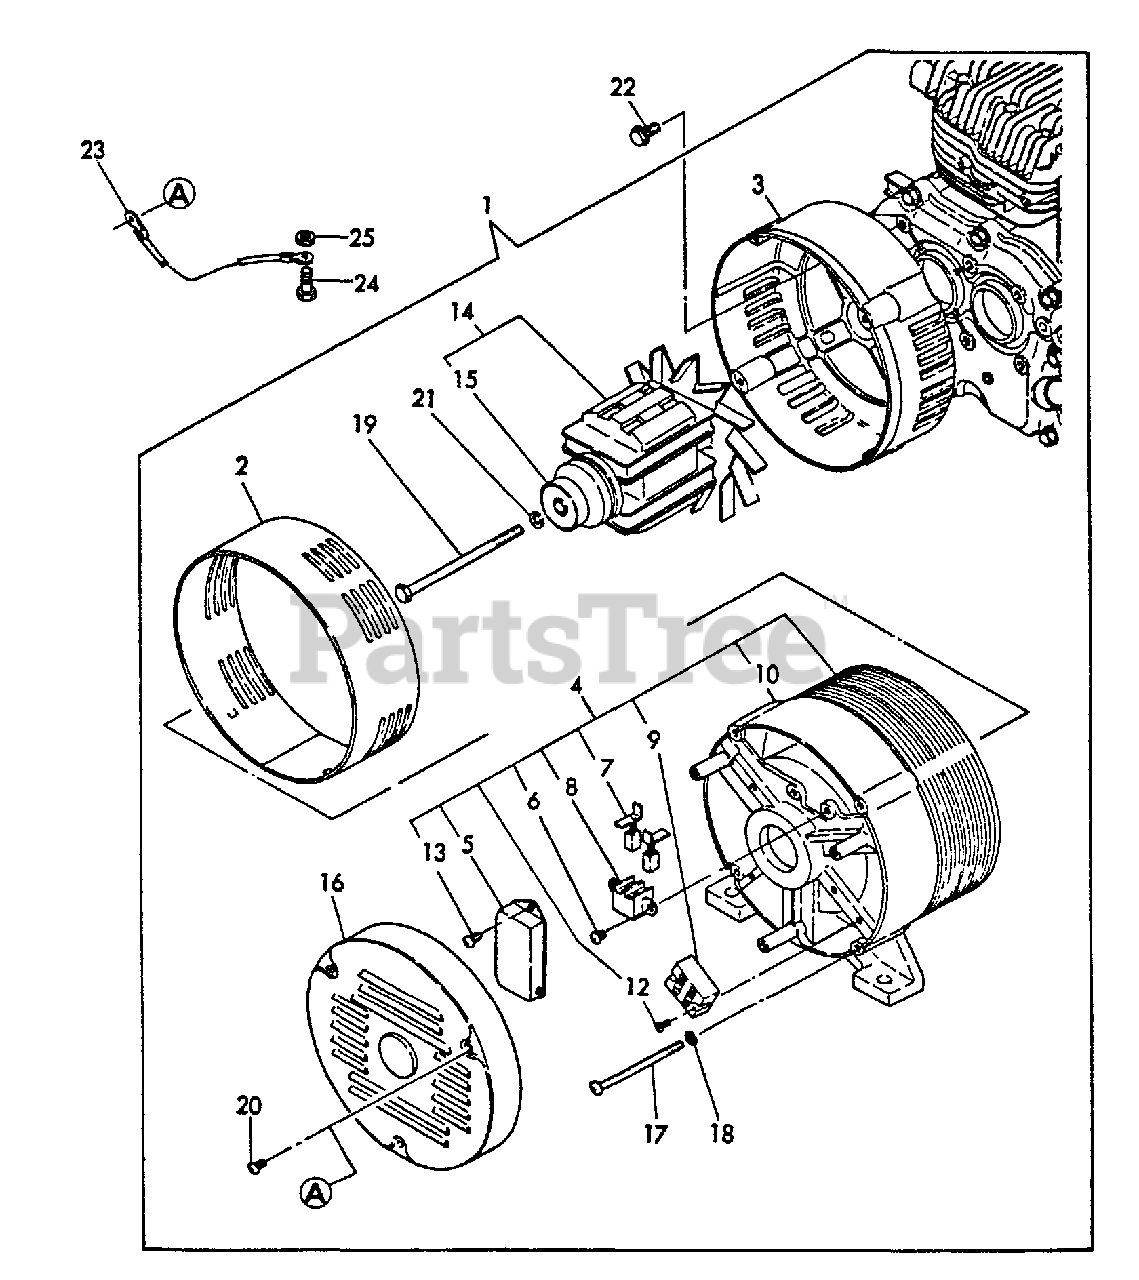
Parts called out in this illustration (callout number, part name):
1	GENERATOR 3.0 KVA
2	CLAMP
3	COVER - FRONT
4	STATOR ASSY
5	A.V.R.
6	SCREW - 5X14
7	BRUSH ASSY
8	HOLDER, BRUSH
9	TERMINAL
10	COVER - REAR
12	SCREW - 5X14
13	SCREW - 4X10
14	ROTOR ASSY
15	BEARING, BALL
16	COVER, END
17	BOLT, THROUGH
18	LOCKWASHER - 6
19	BOLT
20	SCREW - 4X10
21	LOCKWASHER - 10
22	BOLT - 8X20 -- PLATED
23	LEAD - GROUND
24	BOLT - 6X16 -- PLATED
25	LOCKNUT - 6 -- PLATED
